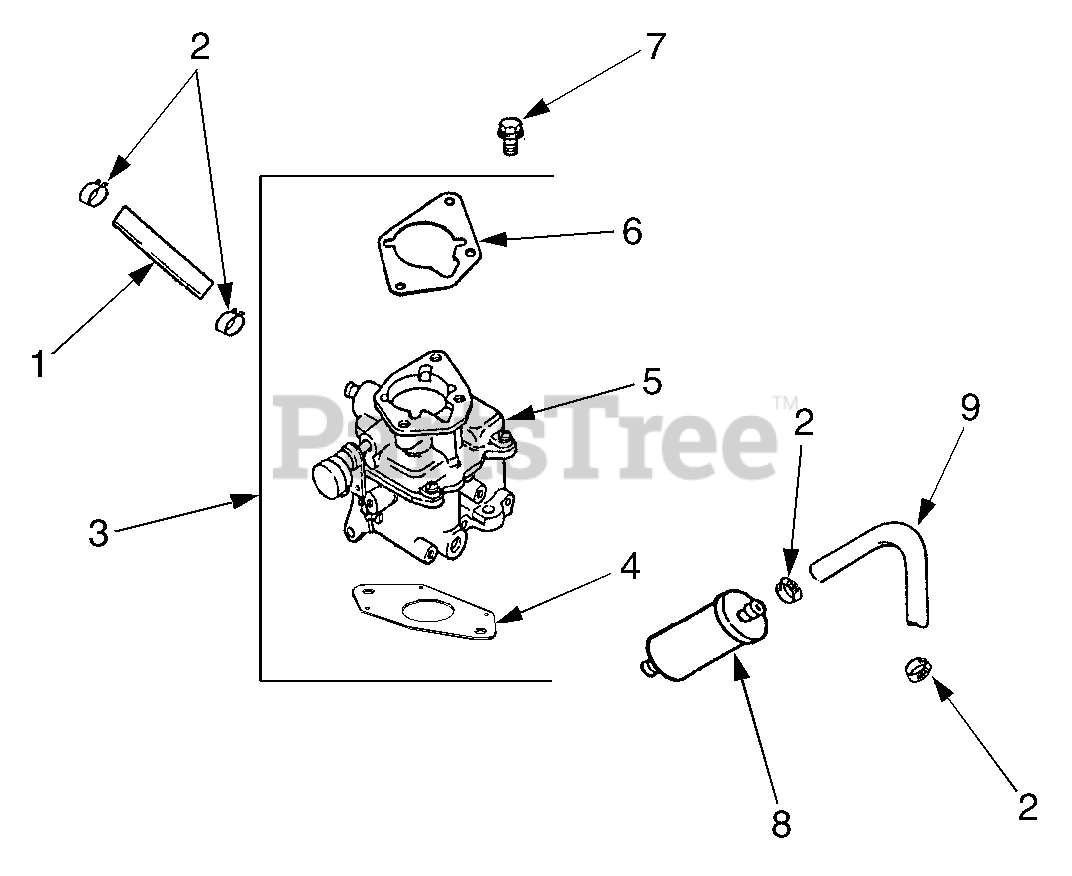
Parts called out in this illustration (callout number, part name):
1	Line, Fuel 24"
2	Clamp, Hose
3	Kit, Carburetor w/Gasket
4	Gasket, Carburetor
5	Carburetor Assembly
6	Gasket, Air Cleaner Base
7	Screw, Hex Flange
8	Filter, Fuel
9	Line, Fuel 24"
